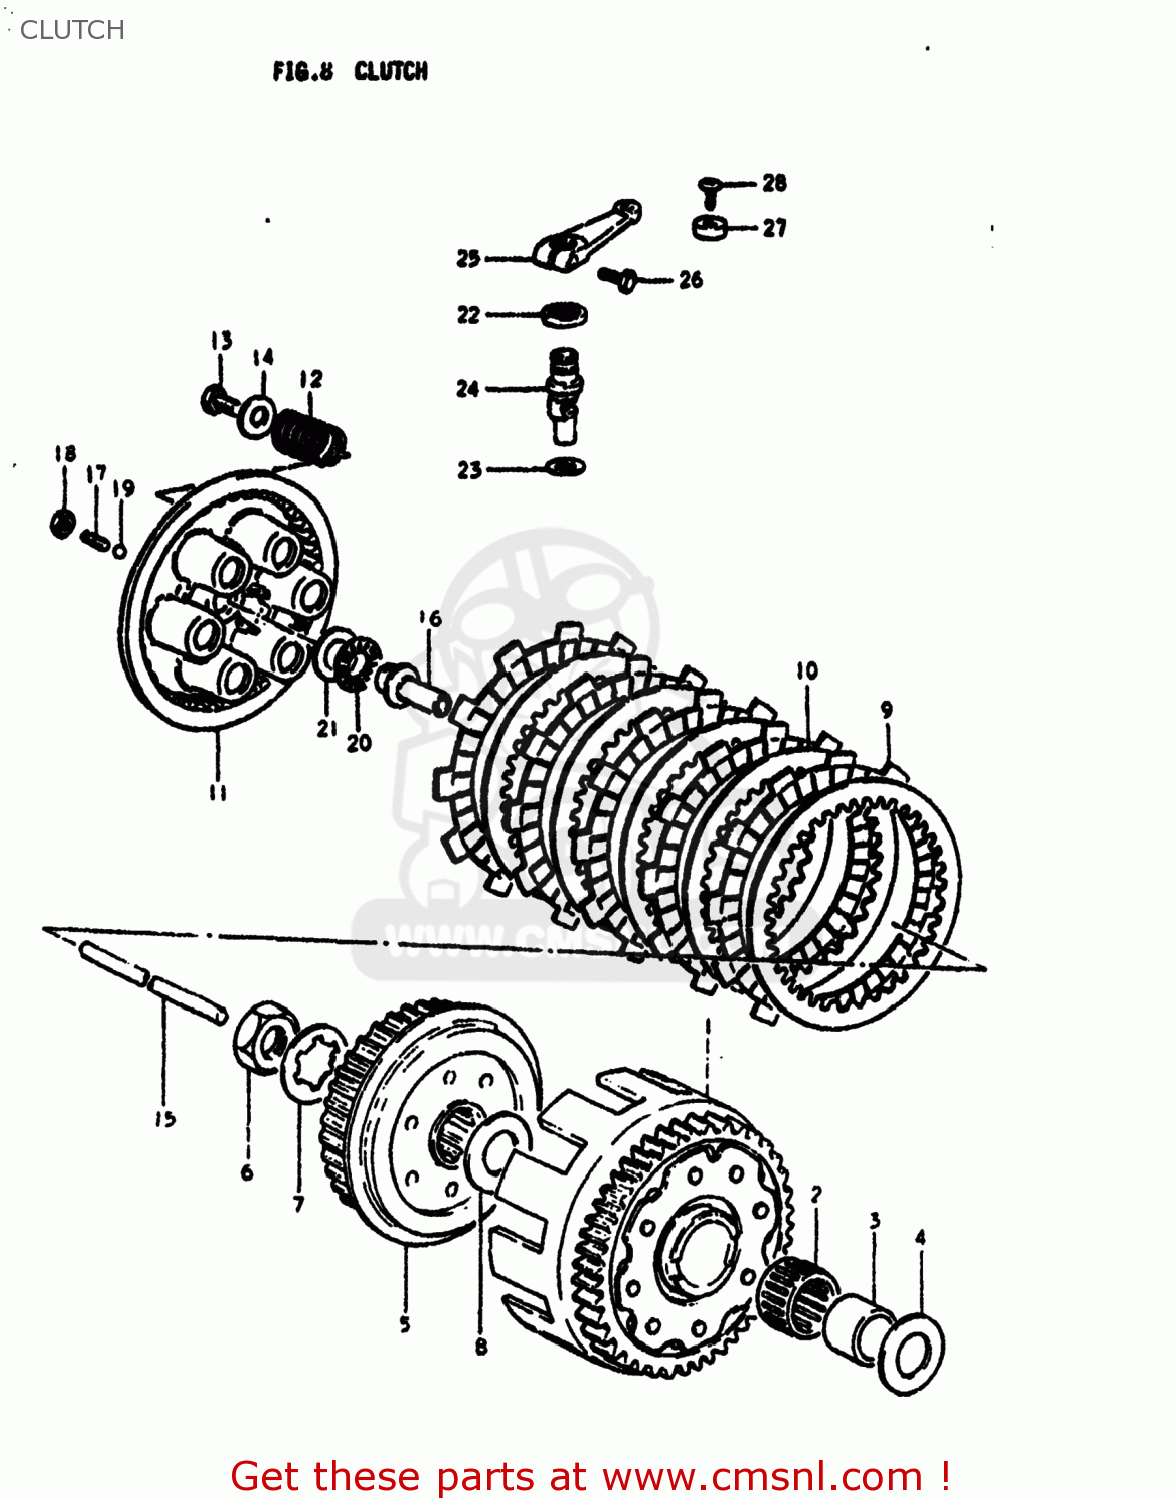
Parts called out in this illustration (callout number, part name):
1	GEAR ASSEMBLY,PRIMARY DRIVE
2	BEARING(30X35X19.8)
3	SPACER
4	WASHER
5	HUB,CLUTCH SLEEVE
6	NUT
7	WASHER,LOCK
8	WASHER
9	PLATE,CLUTCH DRIVE (MCA)
10	PLATE,CLUTCH DRIVEN (NAS)
11	DISC,CLUTCH PRESSURE
12	SPRING
13	BOLT, UPPER
14	WASHER
15	ROD,CLUTCH PUSH
16	PIECE,CLUTCH PUSH
17	SCREW
18	NUT 6MM
19	BALL
20	BEARING(15X28X2)
21	WASHER
22	OIL SEAL
23	WASHER (14.2X22X1)
24	SHAFT,CLUTCH RELEASE C
25	ARM,CLUTCH RELEASE
26	BOLT
27	GUIDE,CLUTCH CABLE
28	SCREW
